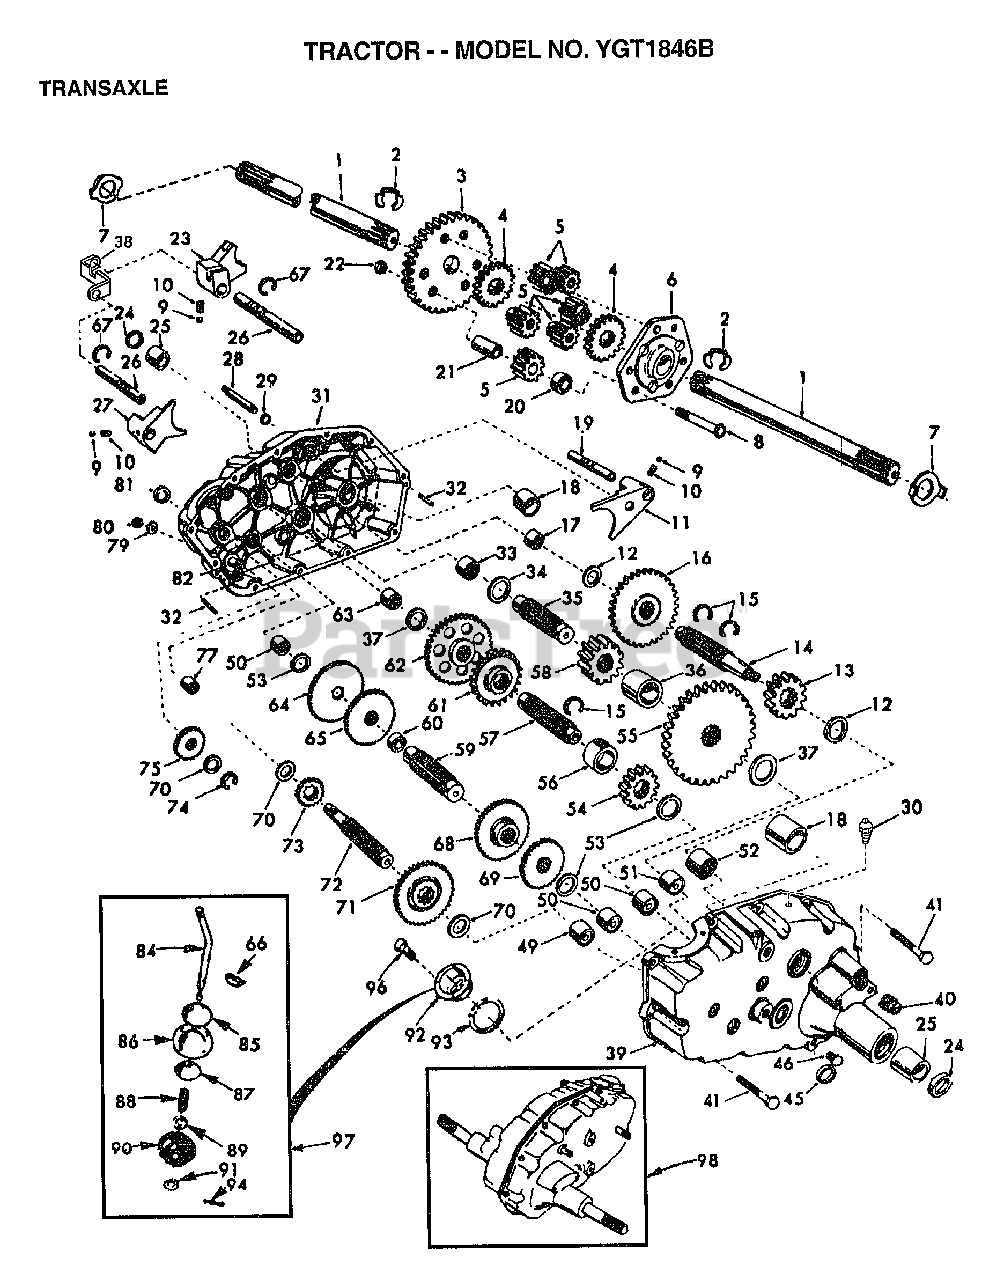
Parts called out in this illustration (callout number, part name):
1	SHAFT.AXLE.T
2	KLIP RING
3	FINAL GEAR T
4	DIFF GEAR T
5	DIFF PINION T
6	DIFF CARRIER T
8	BOLT
11	SHIFT FORK T
12	WASHER .T
13	RED PINION T
14	SHAFT BRAKE GT
15	SNAP RING T
16	GEAR T
17	"T, BEARING"
18	BEARING
19	SHAFT
20	SPACER T
21	PINION RS
22	GRIPCO NUT
23	FORK T
24	OIL SEAL STD
25	BRNG. T
26	SHIFT FORK SHAFT
27	SHIFT FORK T
28	SHIFT SHAFT
29	SEAL T
30	VALVE M
31	GEARCASE RH W/BER
32	PIN T
33	NEEDLE BRNG T
34	RACE T
35	GEAR SHAFT T
37	RACE T
38	GAT.LOWE.SHIFT.VGT
39	GEARCASE LH W/BER
40	PLUG PIPE
41	BOLT.5/16-18X1.25
45	SEAL T
49	"TI, BEARING"
50	NEEDLE BRNG T
51	NEEDLE BRNG T
52	"STD, BEARING"
53	BRNG RACE
54	RED PINION T
55	RED GEAR T
56	PINION SPACER T
57	GEAR SHAFT T
58	FINAL PINION T
59	GEAR SHAFT T
60	SPACER T
61	RED PINION T
62	RED GEAR T
63	RACE T
64	LOW SPEED GEA T
65	REVERSE GEAR T
66	KEY T
67	KLIP RING
68	INTERMED GEAR T
70	"T, BEARING"
71	CLUSTER GEAR T
72	SHAFT INPUT
73	LO SPEED PINION T
74	KLIP RING
75	IDLER GEAR T
77	NEEDLE BEARING TI
79	WASHER T
80	NUT
81	SEAL STD
82	SHAFT REVERSE IDL
84	GEAR SHIFT LVR T
85	CAP T
86	COVER AND PIN T
87	GUIDE BALL T
88	SPRING TI
89	WASHER
90	SEAL T
91	WASHER
92	GEAR SHIFT GA T
93	GASKET T
94	COTTER PIN
95	SCREW.HX.W.HD.MAC
97	GEAR SHFT LVR T
98	TRANSAXLE ASM 6SP
